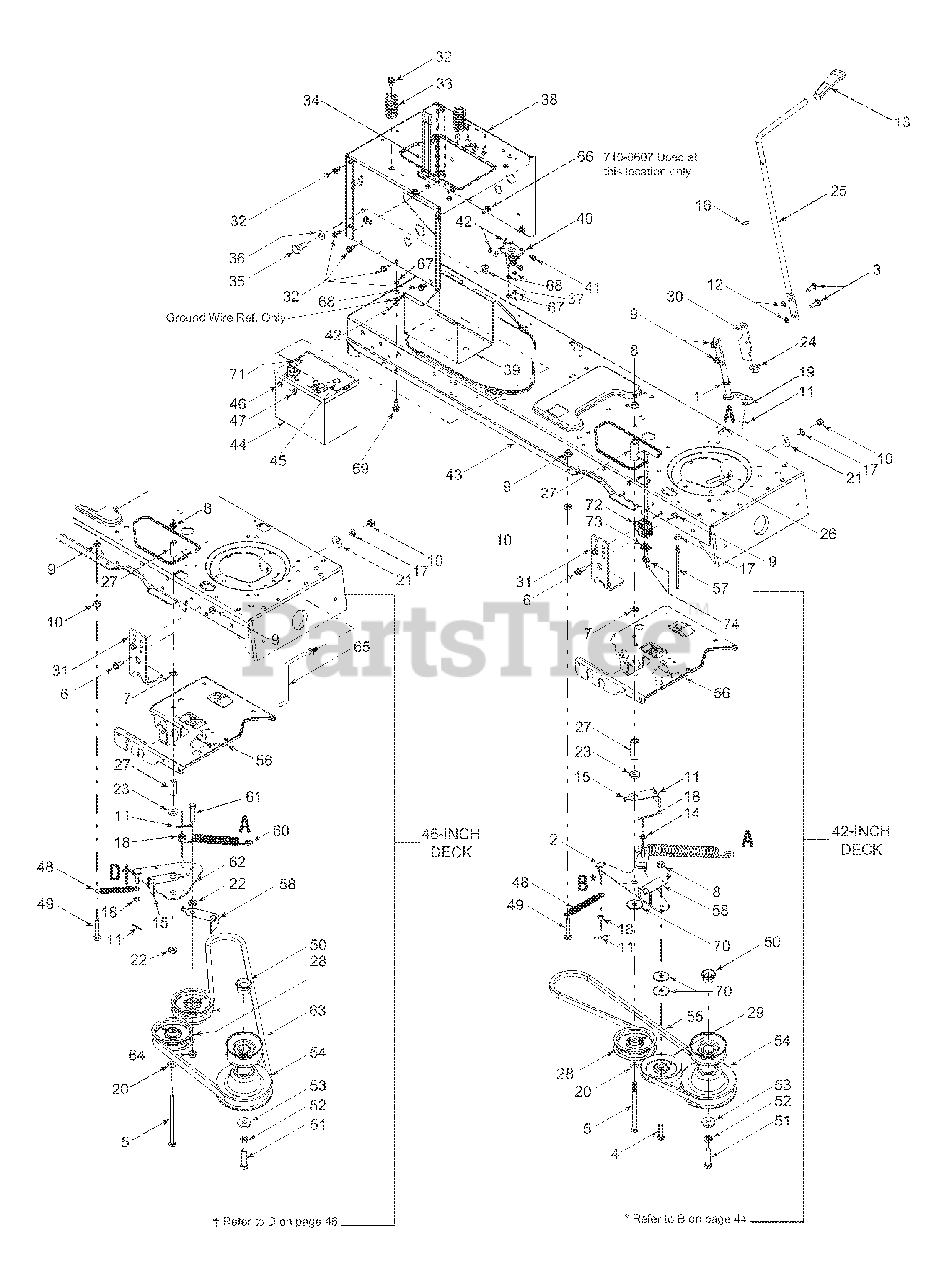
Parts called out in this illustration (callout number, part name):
1	PTO Engage Lever Assembly
4	Hex Cap Screw, 3/8-16 x 1.5
5	Hex Cap Screw, 3/8-16 x 5.5
6	Hex Head Washer Screw, 5/16-18 x .875
7	Push Nut, 3/8
8	Flange Lock Nut, 3/8-16
9	Flange Lock Nut, 5/16-18
10	Hex Nut, 5/16-18
11	Cotter Pin, 1/8 x 1.25
12	Speed Nut, .3125
13	PTO Knob
14	Extension Spring, .75 x 6.75
15	Belt Guard
16	Flat Washer, .510 x .750 x .033
17	Lock Washer, 5/16
18	Flat Washer, .385 x .62 x .063
19	Flat Washer, 5/16
20	Flat Washer, .406 x .875 x .059
21	Bell Washer, .345 x .88 x .060
22	Flat Washer, .407 x .812 x .135
23	Shoulder Spacer, .380
24	Hex Split Flange Bearing, .5
26	Belt Keeper Rod
27	Spacer, 3/8 x 1.54
28	Idler Pulley, 3.5
29	Idler Pulley, 4.0
32	Self Tapping Screw, 5/16-18 x .625
33	Compression Spring, 1.28 x 3.5
34	Battery Strap
35	Shoulder Screw, .625 x .5, 7/16-20
36	Bell Washer, .45 x 1.0 x .062
37	Flange Lock Nut, 7/16-20
41	Self Tapping Screw, 1/4-20 x .5
42	Lock Washer, 1/4
45	Hex Cap Screw, 1/4-20
46	Hex Sems Nut, 1/4-20
47	Wing Nut, 1/4-20
48	Extension Spring, .50 x 5.0
49	Hex Cap Screw, 5/16-18 x 1.75
50	Spacer Cup
51	Hex Head Cap Screw, 7/16-20 x 1.25
52	Lock Washer, 7/16
53	Flat Washer, .450 x 1.25
54	Engine Pulley, 3.56 OD x 5.56
55	PTO Belt (Models w/ 42-inch deck)
57	Keeper Pin, 5/16 x 4.75
58	Belt Guard
60	Extension Spring, .75 x 6.75
61	Hex Cap Screw, 3/8-16 x 1.75
63	PTO Belt (Models w/ 46-inch deck)
64	Flange Lock Nut, 3/8-16
65	Belt Keeper Rod
66	Self-tapping Screw, 5/16-18 x .5
67	Hex Nut, 1/4-20
68	Lock Washer, 1/4
69	Self-tapping Screw, 1/4-20 x .75
70	Flat Washer, .406 x 1.5 x 11 guage
71	Carriage Bolt, 1/4-20 x .75
72	Safety Interlock Switch
73	Switch Plate
74	Screw, #10 x .5
